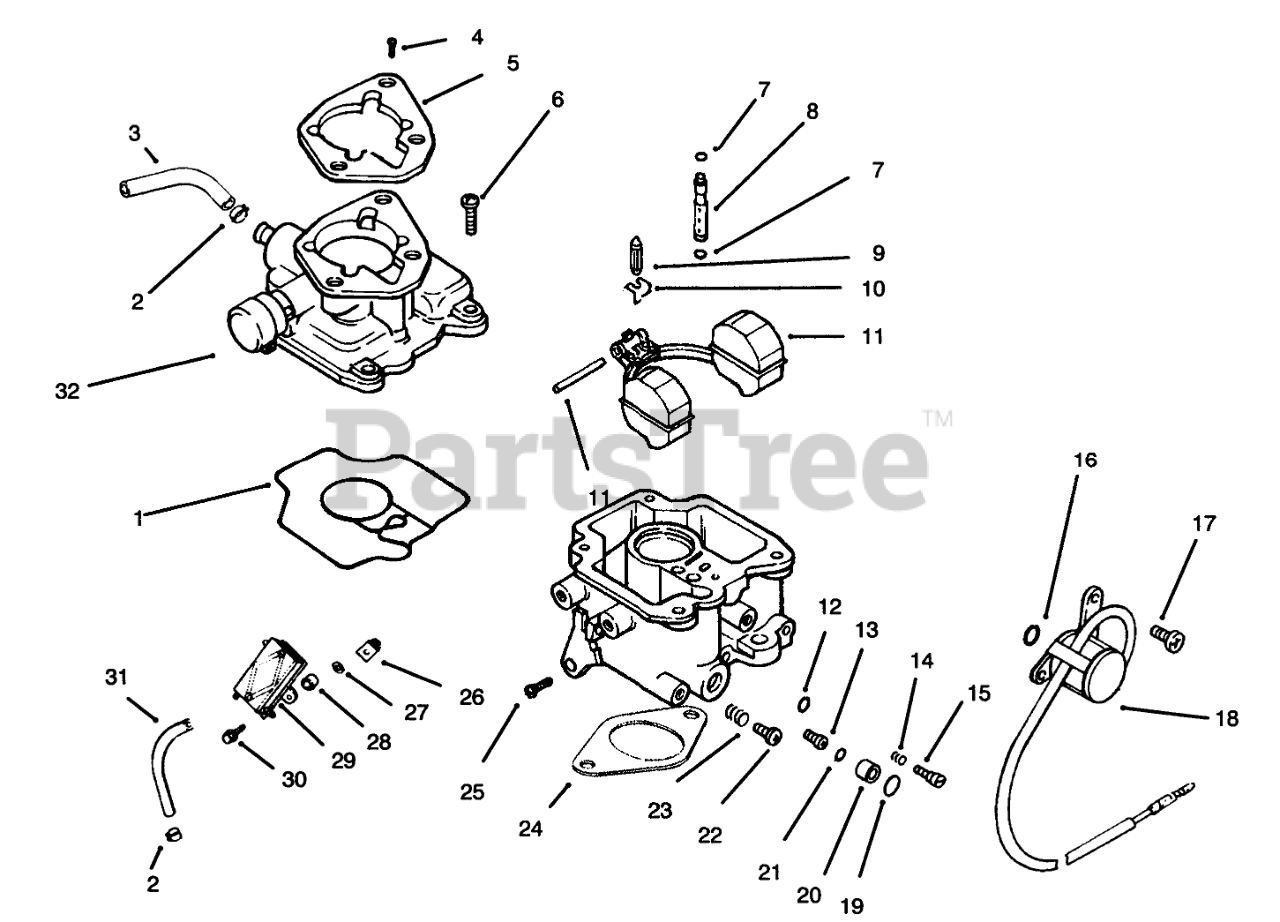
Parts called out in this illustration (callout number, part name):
1	Gasket-Carburetor Body
2	Clamp
3	Line-Fuel
5	Gasket-Air Cleaner
7	"O"Ring
8	Jet-Slow
9	Valve-Inlet Needle
10	Clip-Inlet Needle Valve
11	Kit-Float Repair
12	"O"Ring
13	Jet-Main
14	Spring-Idle Adjust
15	Needle-Idle Adjust
16	"O"Ring
18	Solenoid
19	"O"Ring
20	Seat-Solenoid
21	"O"Ring
22	Screw-Idle Speed Adjust
23	Spring-Idle Speed Adjust
24	Gasket-Carburetor
25	Screw-Throttle Stop
27	Washer
29	Pump-Fuel
31	Line-Fuel 15-1/2"
32	Kit-Choke Repair (Incl. Ref. #33
